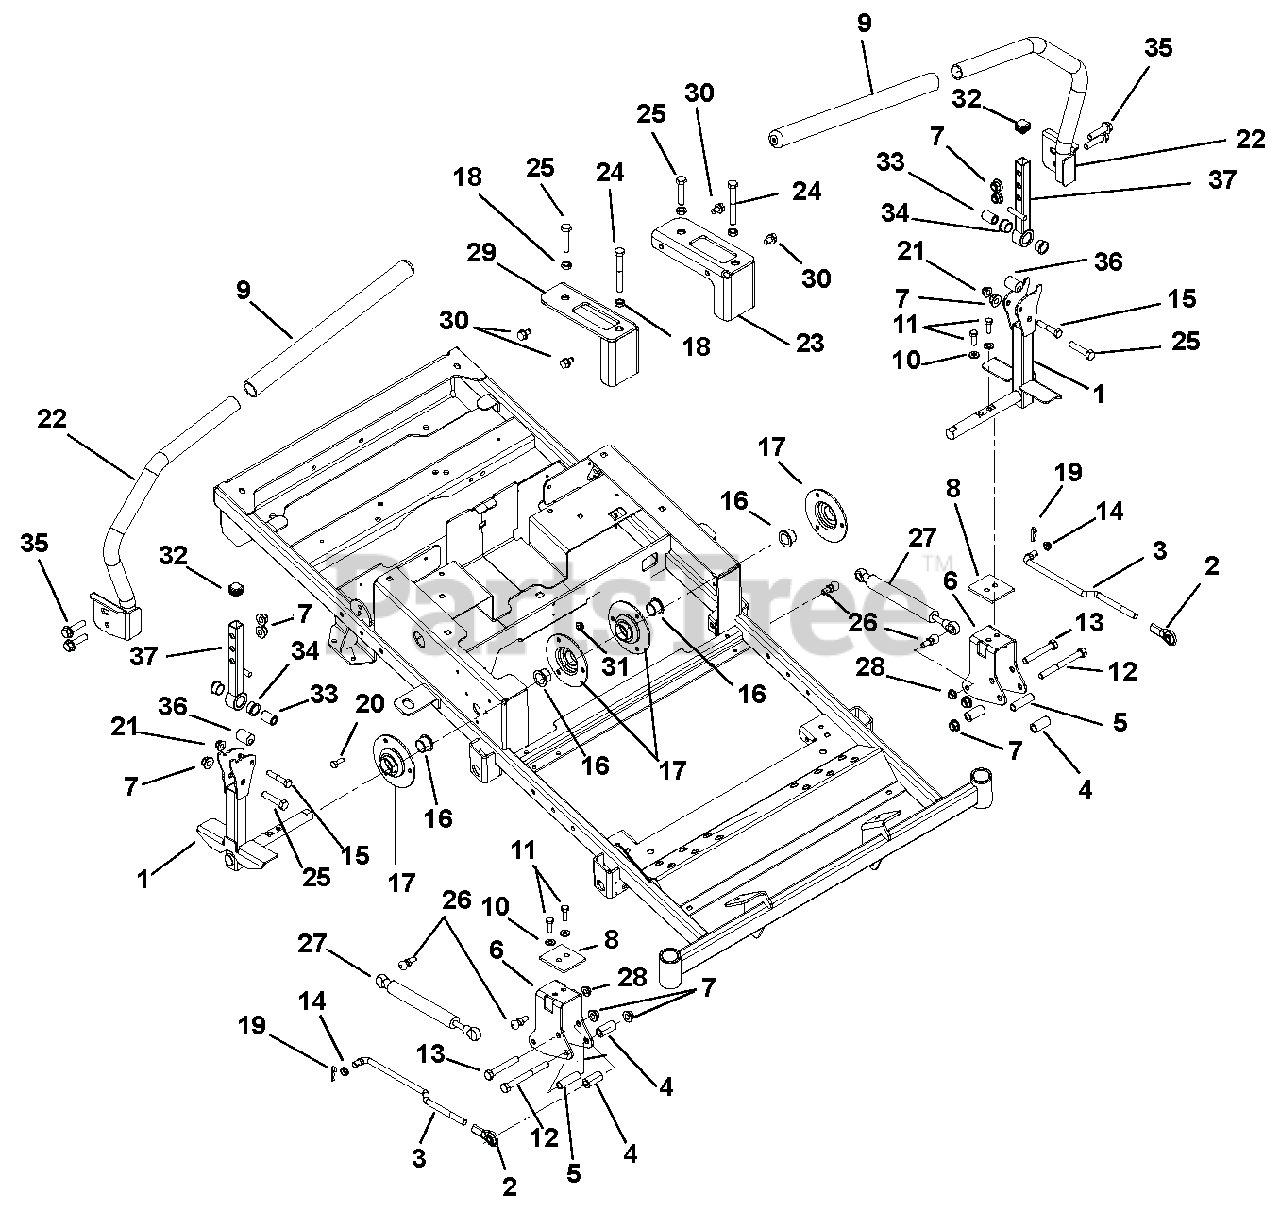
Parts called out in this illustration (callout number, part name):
1	WMT, CONTROL ARM
2	ROD END, .38 RH
3	LINK, TRANSMISSION
4	BSHG, SPCR .390X.625X1.25 PM
5	SPACER, STEERING
6	BRKT, STEERING
7	@NUT-LK-NYL-FLG .38-16 YWZC
8	PLATE, STEERING REINFORCING
9	GRIP, HANDLEBAR 15" FOAM
10	@WSHR-LK .31X.078 REG YWZC
11	BLT-HEX .31-18X1.00 GR8 YWZC
12	@BLT-HEX .38-16X3.75 GR5 YWZC
13	@BLT-HEX .38-16X2.50 GR5 YWZC
14	BUSHING, POLYLINER-.38 SNAPIN
15	@BLT-HEX .31-18X1.75 GR5 YWZC
16	BSHG-FLG .750X1.000X.625X1.250
17	BEARING FLANGE
18	NUT-HEX-JAM .375-16 YWZC
19	PIN-HAIR INT .08X.18X1.18 YWZC
20	@BLT-HEX .25-20X.75 GR5 YWZC
21	@NUT-LK-NYL-FLG .31-18 YWZC
22	WMT, STEERING HANDLE RH
23	BRACKET, LH SPEED CONTROL
24	BLT-HEX .38-16X3.00 GR5 FTH YZ
25	BLT-HEX .375-16X1.750 FTD YWZC
26	STUD- BALL
27	DAMPER, CONTROL
28	@NUT-LK-TOP-FLG .31-18 YWZC
29	BRACKET, RH SPEED CONTROL
30	@SCR-TAP .31-18X.50 HWH TR YWZ
31	@NUT-LK-TOP-FLG .25-20 YWZC
32	CAP PLUG, SQ 3/4-14-20 RIBBED
33	SPACER, .375X.625X.970 (PM)
34	BSHG-FLG, .625X.75X.450X.875
35	BLT-SERHFWH .375-16X1.25 YWZC
36	BSHG, ECCENTRIC .328X.750X.970
37	WMT, UPPER CONTROL ARM
